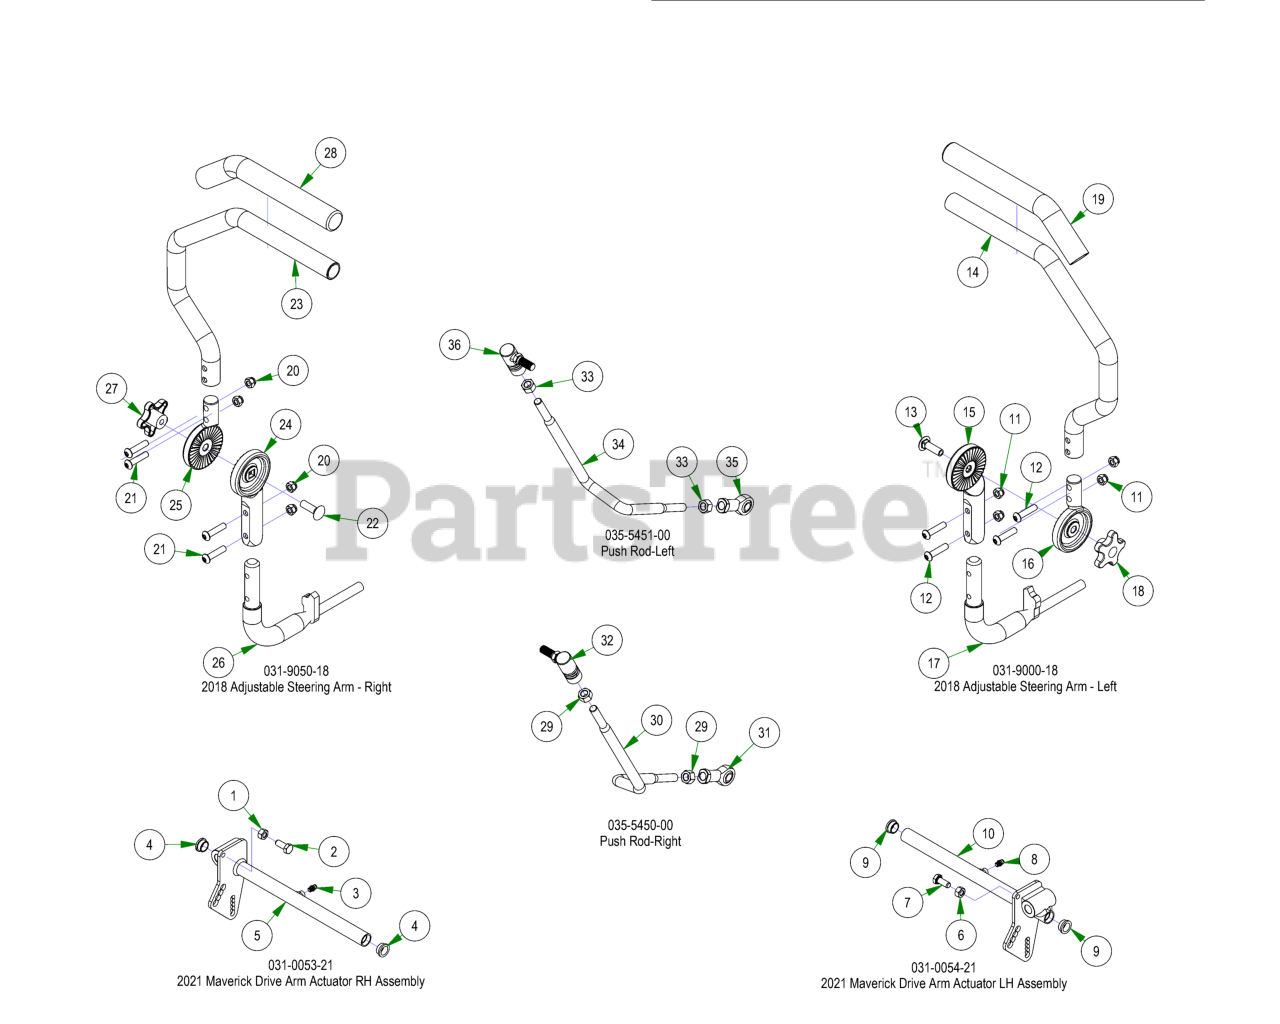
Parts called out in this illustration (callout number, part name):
1	5/16-18 HEX NUT ZINC
2	5/16-18 X 3/4 HEX CAP SCREW (GR.5) ZINC
3	1/4" Press in Grease Fitting
4	2019 Drive Arm Bushing
5	2021 Drive Actuator RH Weldment
6	5/16-18 HEX NUT ZINC
7	5/16-18 X 3/4 HEX CAP SCREW (GR.5) ZINC
8	1/4" Press in Grease Fitting
9	2019 Drive Arm Bushing
10	2021 Drive Actuator LH Weldment
11	5/16-18 NYL INS L/N ZC
12	5/16-18 UNC X 1-3/8" BHCS, TORX DRIVE, GR 5
13	3/8-16 X 1-1/4 CARRIAGE BOLT ZINC
14	Upper Tube-Adjustable Steering
15	2018 Lower Adjuster - Steering Arm- Left
16	2018 Upper Adjuster - Steering Arm- Left
17	Steering Arm Elbow (Left)
18	Black Knob for Adjustable Steering Arm
19	Rubber Grip
20	5/16-18 NYL INS L/N ZC
21	5/16-18 UNC X 1-3/8" BHCS, TORX DRIVE, GR 5
22	3/8-16 X 1-1/4 CARRIAGE BOLT ZINC
23	Upper Tube-Adjustable Steering
24	2018 Lower Adjuster - Steering Arm- Right
25	2018 Upper Adjuster - Steering Arm- Right
26	Steering Arm Elbow (Right)
27	Black Knob for Adjustable Steering Arm
28	Rubber Grip
29	3/8" Fine Threaded Jam Nut
30	Push Rod - Right (Rod Only)
31	Spherical Rod End - Outlaw
32	Quick Release Ball Joint
33	3/8" Fine Threaded Jam Nut
34	Push Rod LH (Rod Only)
35	Spherical Rod End - Outlaw
36	Quick Release Ball Joint
